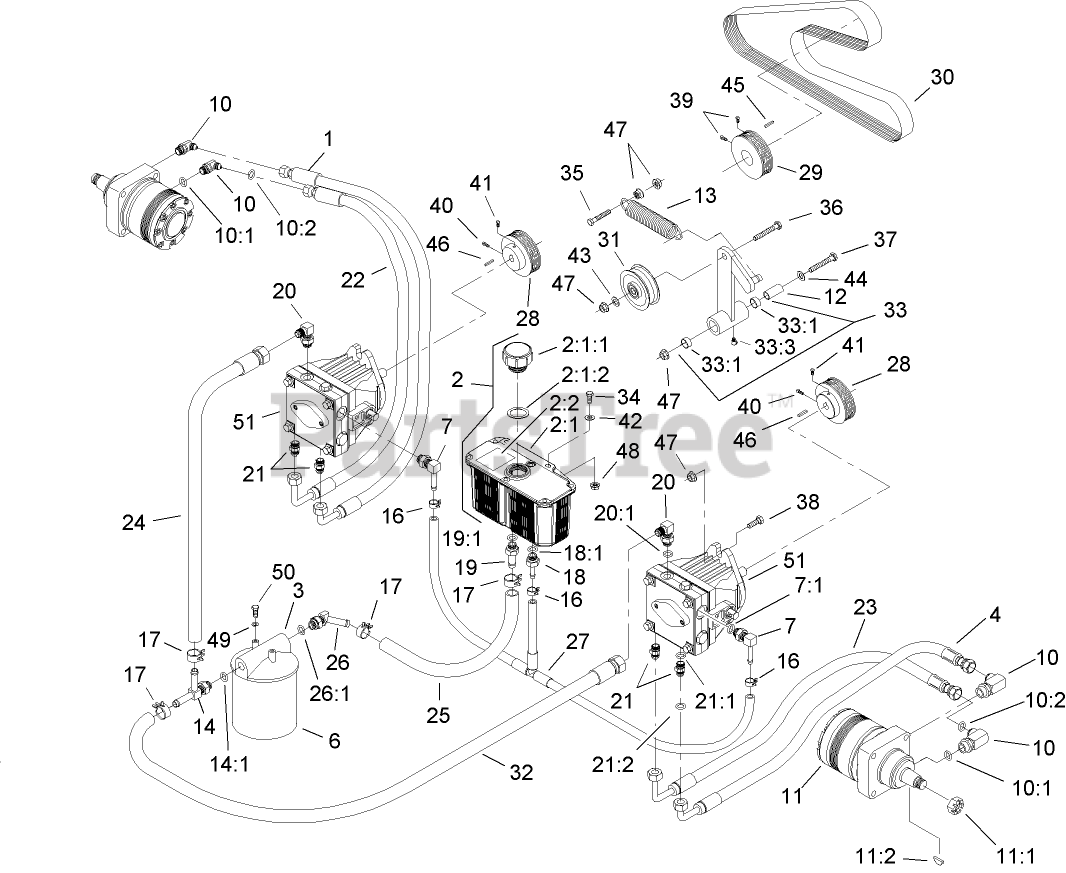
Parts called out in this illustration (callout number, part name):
1	HYD HOSE ASM
2	HYD Reservoir ASM
2:1	Reservoir-HYD
2:1:1	CAP-RESERVOIR, HYD
2:1:2	GASKET-CAP
2:2	DECAL-TANK, HYD
3	HEAD-FILTER
4	HYD HOSE ASM
6	FILTER-OIL, HYD
6	FILTER-OIL, HYD (WINTER)
7	ELBOW-90 DEG
7:1	O-RING
10	Fitting-Straight
10:1	O-RING
10:2	O-Ring
11	MOTOR-WHEEL
11:1	NUT-HH
11:2	KEY-WOODRUFF
12	BUSHING-PIVOT, IDLER
13	Spring-Extension
14	ADAPTER-RUN, TEE
14:1	O-RING
16	Clamp-Hose
17	Clamp-Hose
18	Adapter-Straight
18:1	O-RING
19	ADAPTER-STRAIGHT
19:1	O-RING
20	FITTING-ELBOW, 90 DEG
20:1	O-Ring
21	FITTING-STRAIGHT
21:1	O-RING
21:2	O-Ring
22	HYD HOSE ASM
23	HYD HOSE ASM
24	HYD Hose ASM
25	Hose-HYD
26	FITTING-BARBED, 45 DEG
26:1	O-RING
27	HYD Hose ASM
28	SHEAVE
29	SHEAVE
30	BELT-V
31	SHEAVE-IDLER
32	HYD Hose ASM
33	BEARING ARM ASM
33:1	SLEEVE-BEARING
33:3	FITTING-GREASE, 90 DEG
34	SCREW-HH
35	SCREW-HH
36	SCREW-HH
37	SCREW-HH
38	SCREW-HH
39	SCREW-SET
40	SCREW-SET
41	SCREW-SET
42	WASHER-FLAT
43	WASHER-FLAT
44	WASHER-FLAT
45	KEY-SQUARE
47	NUT-HHF, WHIZ
48	NUT-HF
49	WASHER-LOCK
50	SCREW-HH
51	PUMP-HYD
